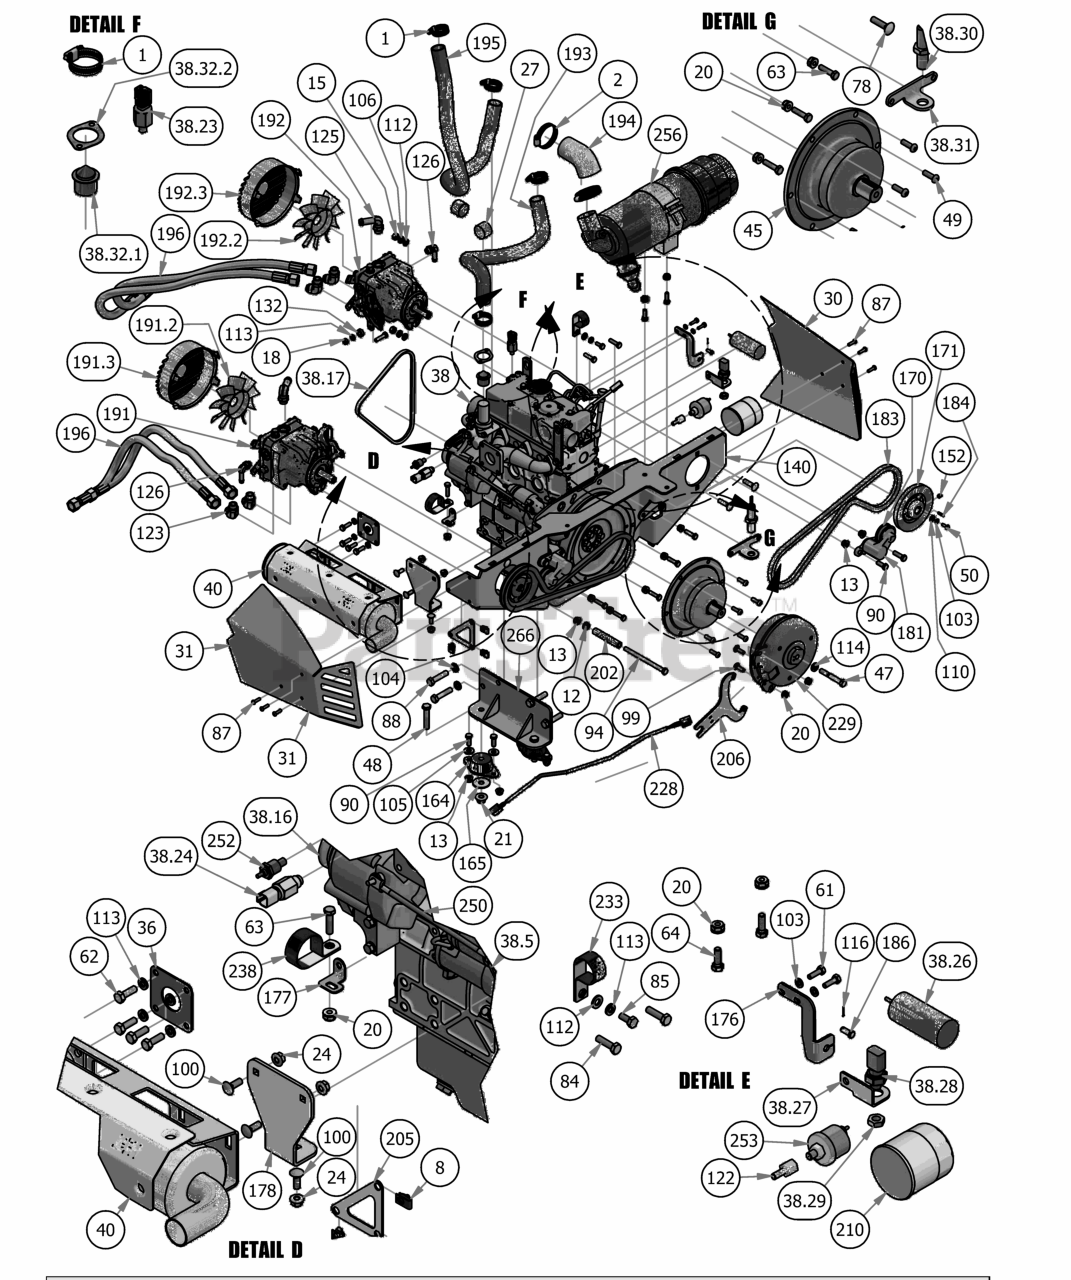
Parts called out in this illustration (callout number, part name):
1	1 1/8" Hose Clamp
2	2-1/2" Hose Clamp
8	1/4-20 Cage Nut
12	3/8" Flange Nut
13	3/8" Nylock Flange Nut
15	3/8" Hex Nut
20	5/16-18 Nylon Flange Nut
21	1/2-13 Nylon Flange Nut
24	5/16" Flange Nut
27	2019 Plastic Mesh Hose Loom
30	2019 Horizontal Pump Cover - Right
31	2019 Horizontal Pump Cover - Left
36	Diesel Muffler Gasket
38	24.7 hp Perkins Engine
38.17	Diesel Engine Belt
38.23	Oil Pressure Sensor
38.24	Coolant Temperature Sensor
38.26	Fuel Shutdown Solenoid
38.27	Barometric Pressure Sensor Bracket
38.28	Barometric Pressure Sensor
38.29	Pressure Sensor Nut for 1100cc Diesel
38.30	Crank Sensor w/ nut
38.31	Crank Sensor Bracket
38.32.1	1100cc Diesel Thermostat
38.32.2	1100cc Diesel Thermostat Gasket
40	2019 Renegade 1100cc Diesel Muffler
45	2019 Diesel Stub Shaft Double V
47	7/16"-20 x 3" Hex Bolt Gr. 8
48	1/2" x 3" Hex Bolt
49	5/16-18 x 1 Button Head Torx
50	M6-1.0 X 16MM Hex Bolt
61	M6x1.0x 20mm 8.8 Hex Bolt
62	M8 x 1.25 x 25mm Hex Head Bolt
63	5/16 x 1 1/4 Hex Bolt
64	5/16" x 1" Bolt
78	3/8 x 1 1/2 Carriage Bolt
80	3/8" x 1 1/4" Hex Bolt
84	M8 x 1.25 x 30mm Hex Head Bolt
85	M8x1.20x20MM Hex head bolt
87	Hexagon Socket Button Head Cap Screw
88	12mm Bolt- Diesel
90	3/8" x 1" Hex Bolt
94	3/8-16 x 5 1/2 Hex Bolt
99	5/16" x 1" Carriage Bolt
100	5/16" x 7/8" Carriage Bolt
103	1/4" Lock Washer
104	1/2" Lock Washer
105	3/8" Flat Washer
106	3/8" Lock Washer
110	1/4" Flat Washer
112	5/16" Flat Washer
113	5/16" Lock Washer
114	7/16" Lock Washer
116	3/32 X 1/2 Cotter-pin
122	8mm x 1/8 mpt Adaptor
123	2019 Outlaw 90 Degree Pump Fitting #6801-10-08
125	90 Degree Fitting, 1/2 x 3/4, 4601-8-8
126	90 Degree Fitting, 3/8 s 9/16
132	ACS Spacer 3/4x3/8x1/4
140	2019 Diesel Pump Plate - Weldment
152	5/16-24 X 3/8 Set Screw
164	Rubber Compression Mount
165	Snubbing Washer
170	2019 Renegade Horizontal Pump Idler Pulley
171	5" Pump Pulley
176	Diesel Throttle Bracket 4 Tier
177	Diesel Radiator Hose Clamp Bracket
178	2019 Diesel Muffler Bracket
181	Horizontal Tensioner
183	2019 Renegade Pump Belt
184	5mm x 1.25" Key
186	1/4-5/8 Clevis Pin
191	2019 Rogue/Renegade Left Pump 16cc
191.2	Hydraulic Fan
191.3	Fan Guard 6" Fits wheel Motor Pumps
192	2019 Outlaw Renegade Right Pump 16cc
192.2	Hydraulic Fan
192.3	Fan Guard 6" Fits wheel Motor Pumps
193	2019 Diesel Radiator Hose Upper
194	2019 Diesel Air intake Hose
195	2019 Diesel Radiator Hose Lower
196	2019 Renegade Hydro Hose
202	3/8 hose 4" long
205	Pump Plate Clip Nut Holder
206	2019 Outlaw Renegade Clutch Bracket
210	CAT Oil Filter
228	Clutch Pigtail
229	Clutch for Diesel/Vanguard
233	Diesel Hydraulic Hose Clamp
238	Diesel Clamp 1 3/4" Vinyl
250	Red Battery Cable Alternator to Starter Cable
252	Coolant Temperature Sender
253	Oil Pressure Guage with Sender
256	Enginaire Canister VLR-Complet
266	2019 Diesel Motor Mount - Weldment
